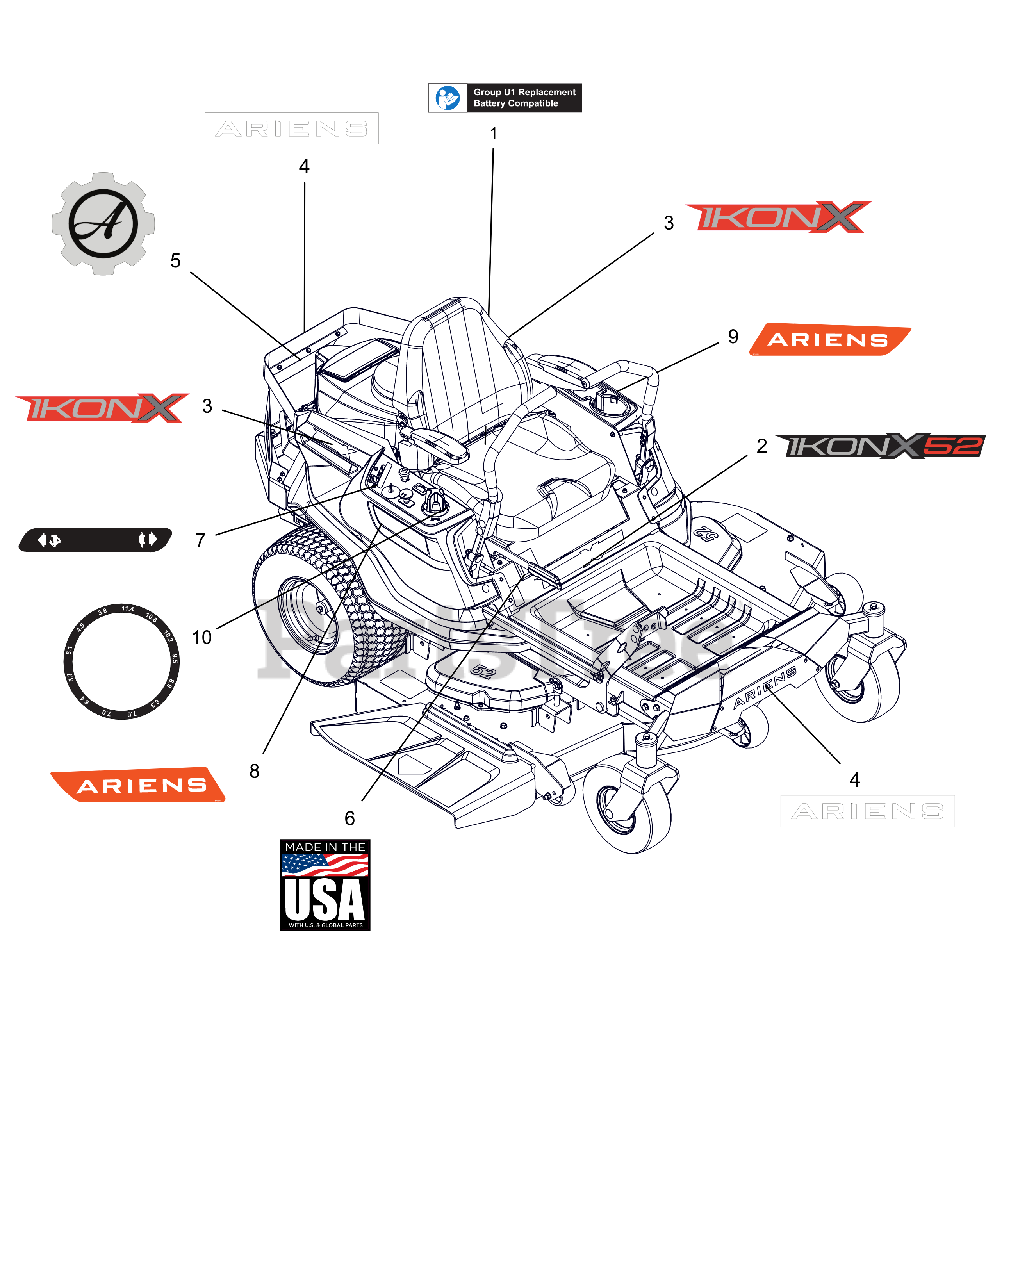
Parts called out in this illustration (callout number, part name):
1	DECAL, U1 BATTERY REPLACEMENT
2	DECAL, IKON-X 52"
3	DECAL, IKON
4	DECAL - ARIENS 9.625"
5	DECAL, ARIENS-GEAR BADGE -THK
6	DECAL, MADE IN USA
7	DECAL, DASH DECAL
8	DECAL, FENDER RH
9	DECAL, FENDER LH
10	DECAL, CUT HEIGHT - IKON CE
